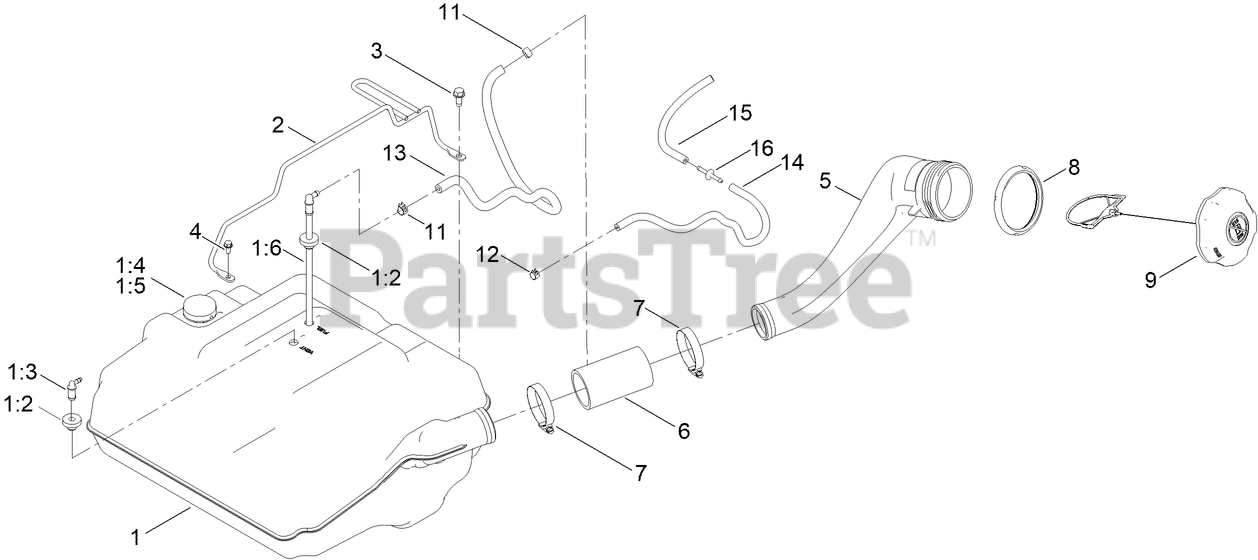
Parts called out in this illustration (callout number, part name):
1	TANK ASM-FUEL
1:2	BUSHING
1:3	FITTING-ELBOW 90
1:4	GROMMET-FUEL
1:5	REMOTE GAUGE ASM
1:6	FITTING - PICKUP, FUEL
2	HOLD DOWN ASM
3	SCREW-HWHTF
4	SCREW-HWH
5	NECK-FILLER, FUEL
6	HOSE-FILLER, FUEL
7	CLAMP-HOSE
8	RING-RETAINING
9	CAP-FUEL, RATCHETING
11	CLAMP-HOSE
12	CLAMP-HOSE
13	HOSE-FUEL
14	HOSE-FUEL
15	HOSE-FUEL
16	ADAPTER ORIFICE
